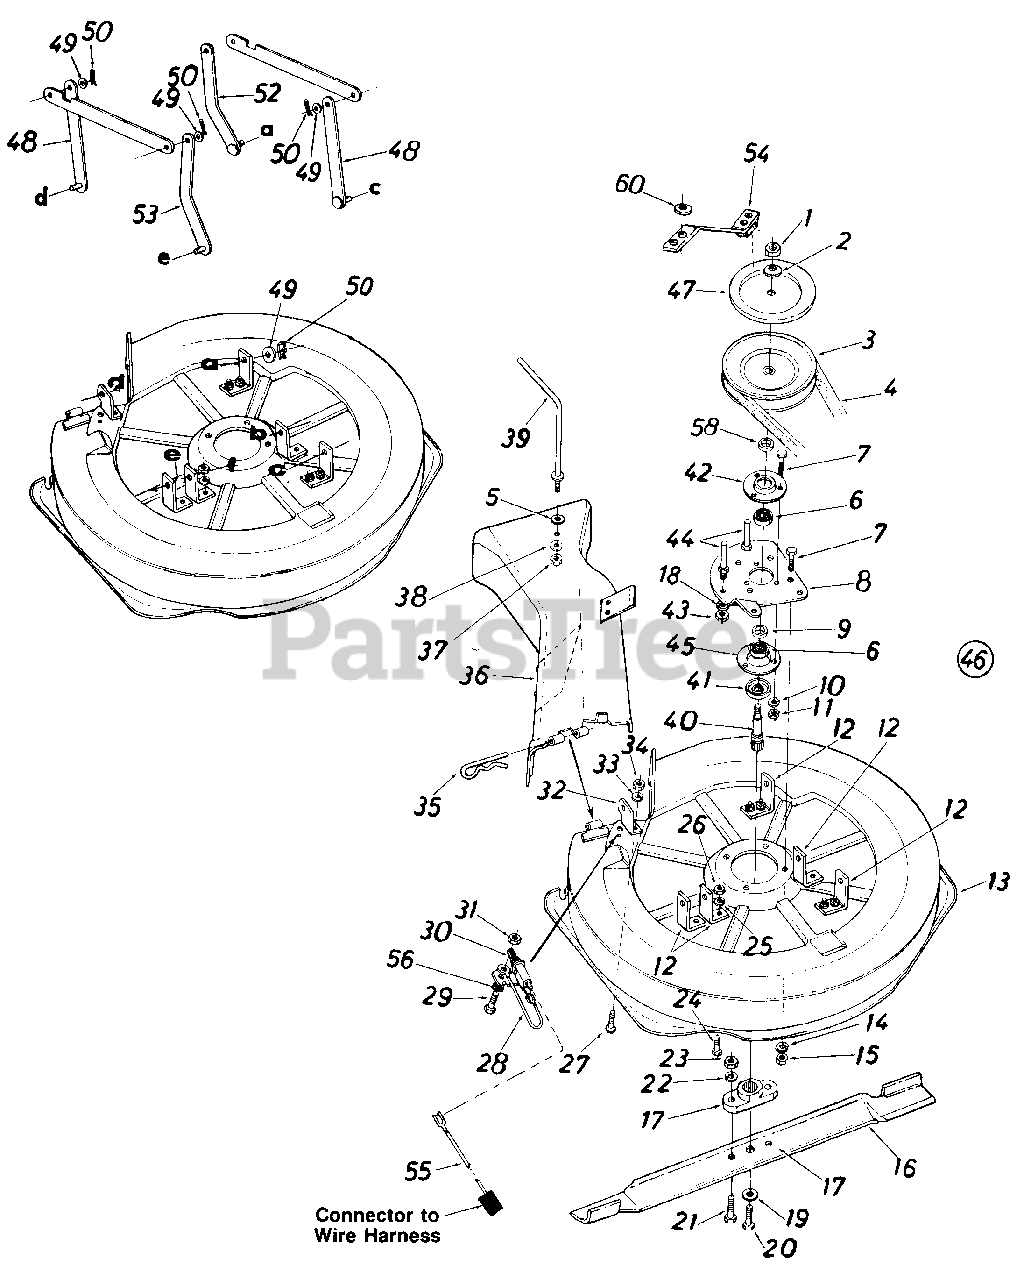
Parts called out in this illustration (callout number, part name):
1	Hex Jam Nut 5/8-18 Thd.
2	Bell-Wash. .630" I.D. x 1.25"
5	Fl-Wash. .344" I.D. x 1.12" O.D.
6	Ball Brg. .787" I.D.
7	Hex Bolt 5/16-18 x .75" Lg.*
8	Spindle Mtg. Plate
9	Spacer
10	L-Wash. 5/16" I.D.
11	Hex Nut 5/16-18 Thd.
12	Hanger Bracket
15	Hex Nut 5/16-18 Thd.
16	30" High Lift Blade-R.H.
17	Blade Adapter
18	L-Wash. 3/8" I.D.
19	Bell-Wash. .39" I.D. x 1.38" O.D.
20	Hex Bolt 3/8-24 x 1.00" Lg.
21	Hex Bolt 5/16-24 x 1.00" Lg.
22	L-Wash. 5/16" I.D.
23	Hex Nut 5/16-24 Thd.
24	Hex Sems Bolt 5/16-18 x .62" Lg.
25	L-Wash. 5/16" I.D.*
26	Hex Nut 5/16-18 Thd.
27	Truss Mach. Scr. 5/16-18 x .75" Lg.
28	Electrical Wire
29	Hex Bolt 1/4-20 x .50" Lg.
30	Safety Switch
31	Hex Nut 1/4-20 Thd.
32	Angle Hanger Brkt.
33	L-Wash. 5/16" I.D.
34	Hex Nut 5/16-18 Thd.
35	Internal Cotter Pin
36	R.D. Chute Deflector
37	Hex L-Nut 5/16-18 Thd.
38	L-Wash. .32" I.D. x .62" O.D.
39	90ø Rod 5/16-18 Thd.
40	Blade Spindle x 5.20
41	Bearing Shield
42	Open Brg. Housing 1.85" I.D.
43	Hex Jam Nut 3/8-16 Thd.
44	Stud 3/8-16 x 3.0" Lg.
45	Brg. Housing 1.85" I.D.
46	30" R.D. Deck Ass'y. Comp.
47	Brake Disc
48	Link Deck Hanger Ass'y.
49	Fl-Wash. .53" I.D. x .93" O.D.
50	Inter. Cotter Pin .50" Dia.
54	Blade Brake Assy
55	Wire Lead
56	L-Wash. 1/4" I.D.
